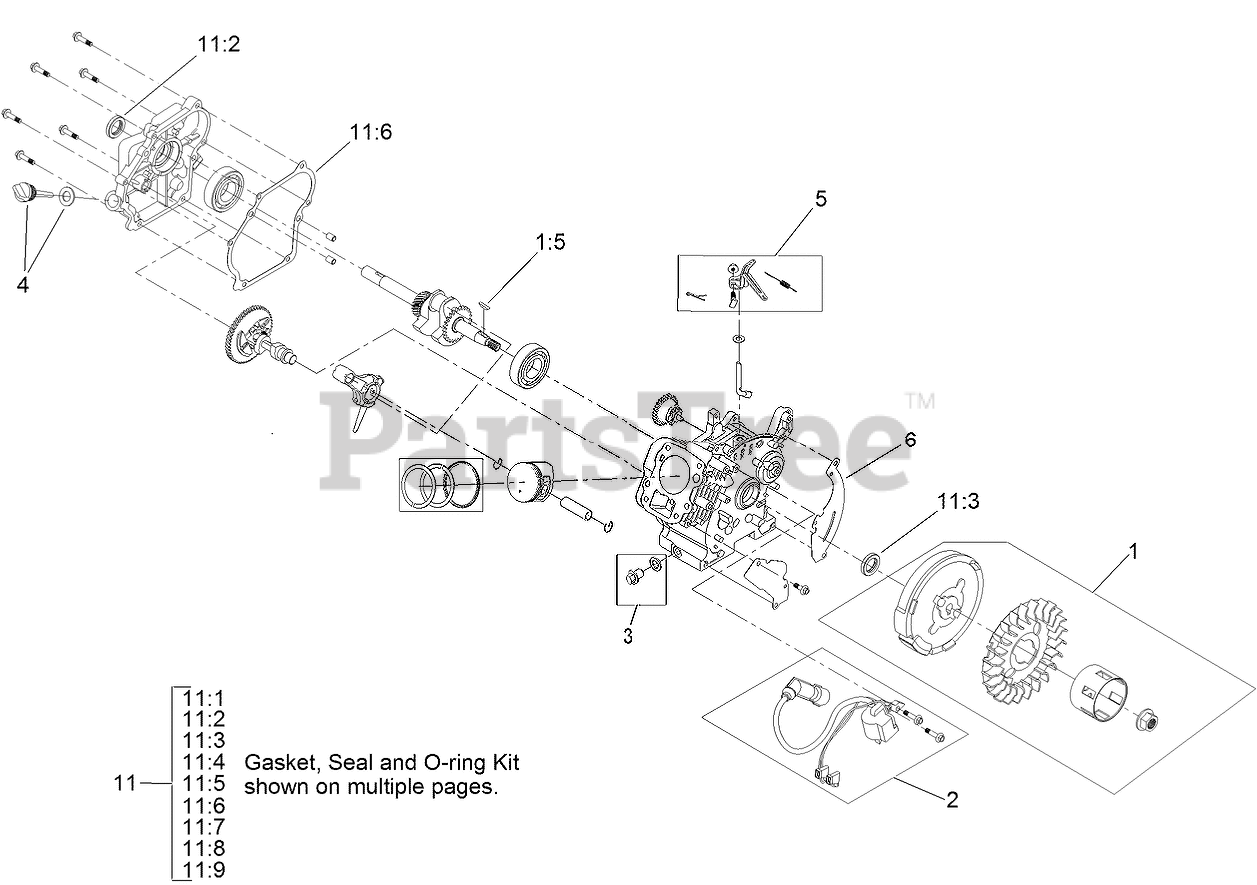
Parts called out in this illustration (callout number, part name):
1	FLYWHEEL AND FAN KIT
1:5	KEY-WOODRUFF
2	IGNITION KIT
3	DRAIN PLUG KIT
4	DIPSTICK AND O-RING KIT
5	GOVERNOR KIT
6	BLOWER SHROUD KIT
11	GASKET, SEAL AND O-RING KIT
11:1	GASKET-EXHAUST
11:2	SEAL-OIL
11:3	SEAL-OIL
11:4	GASKET-COVER, VALVE
11:5	GASKET-HEAD, CYLINDER
11:6	GASKET-COVER, CRANKCASE
11:7	GASKET-INSULATOR
11:8	INSULATOR-CARBURETOR
11:9	GASKET-CARBURETOR
